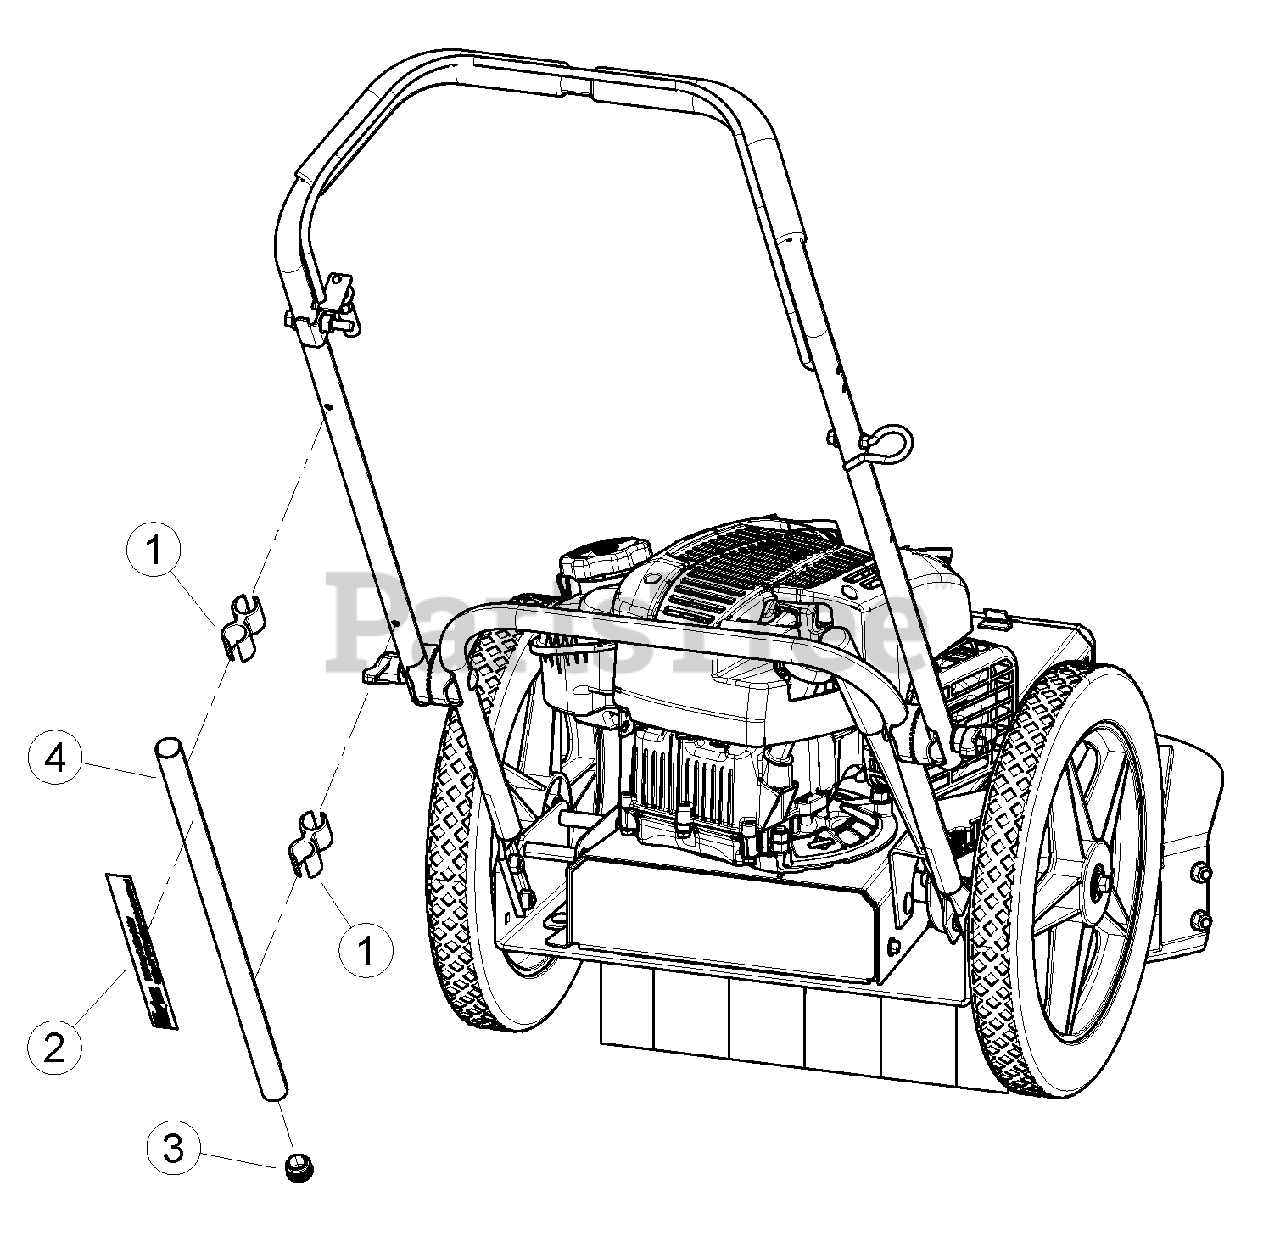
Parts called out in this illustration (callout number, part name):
1	CLIP, LINE TUBE
2	DECAL, TRIMMER LINE HOLDER
3	PLUG, LINE HOLDER TUBE
4	TUBE, TRIMMER LINE HOLDER
